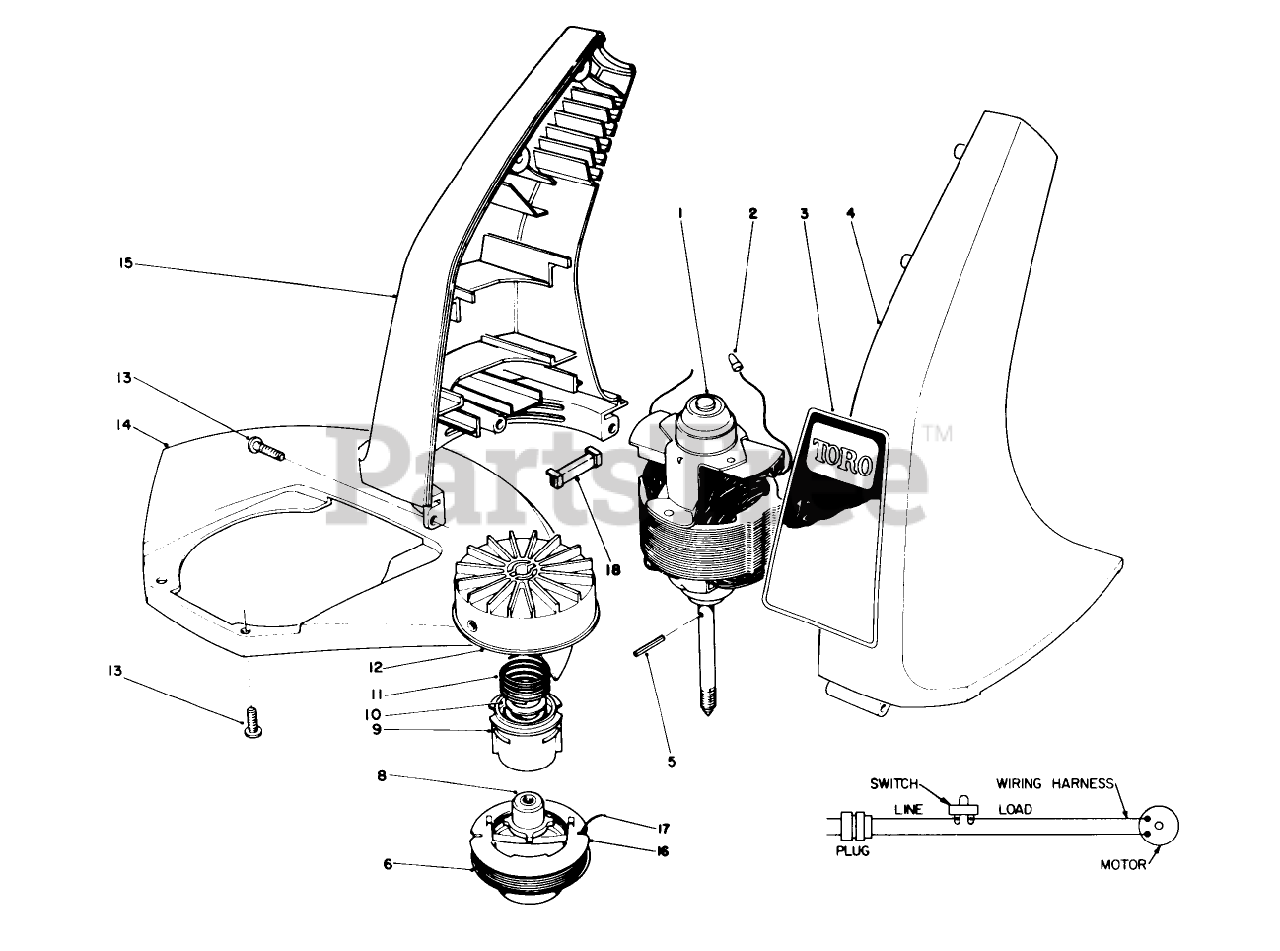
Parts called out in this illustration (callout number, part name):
5	COIL PIN
6	Cutting Line (50 .065" Dia.)
8	DRIVER
9	SPOOL CORE
10	WASHER-FLAT
11	SPRING COMPRESSION
16	SPOOL CAP
